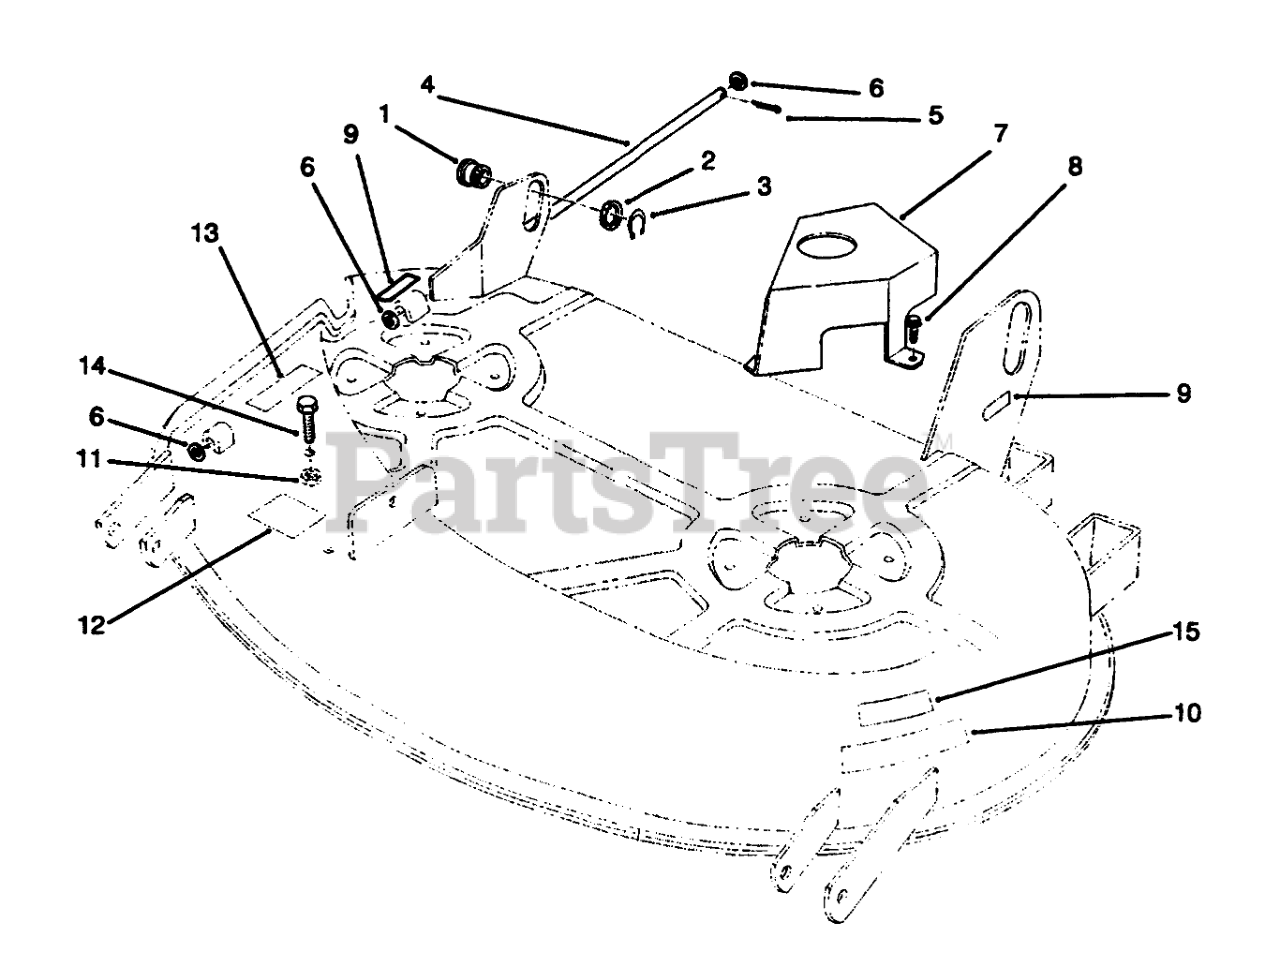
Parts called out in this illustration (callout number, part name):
1	ROLLER-LIFT
2	WASHER
3	RING-RETAINING
5	PIN-COTTER
6	WASHER-PLAIN
7	Cover-Belt
8	SCREW-HWHTF
9	Decal-Attach-A-Matic
10	DECAL - DANGER
11	NUT-LOCK, NI
12	Decal-Routing
13	DECAL-DANGER
14	SCREW-HH
